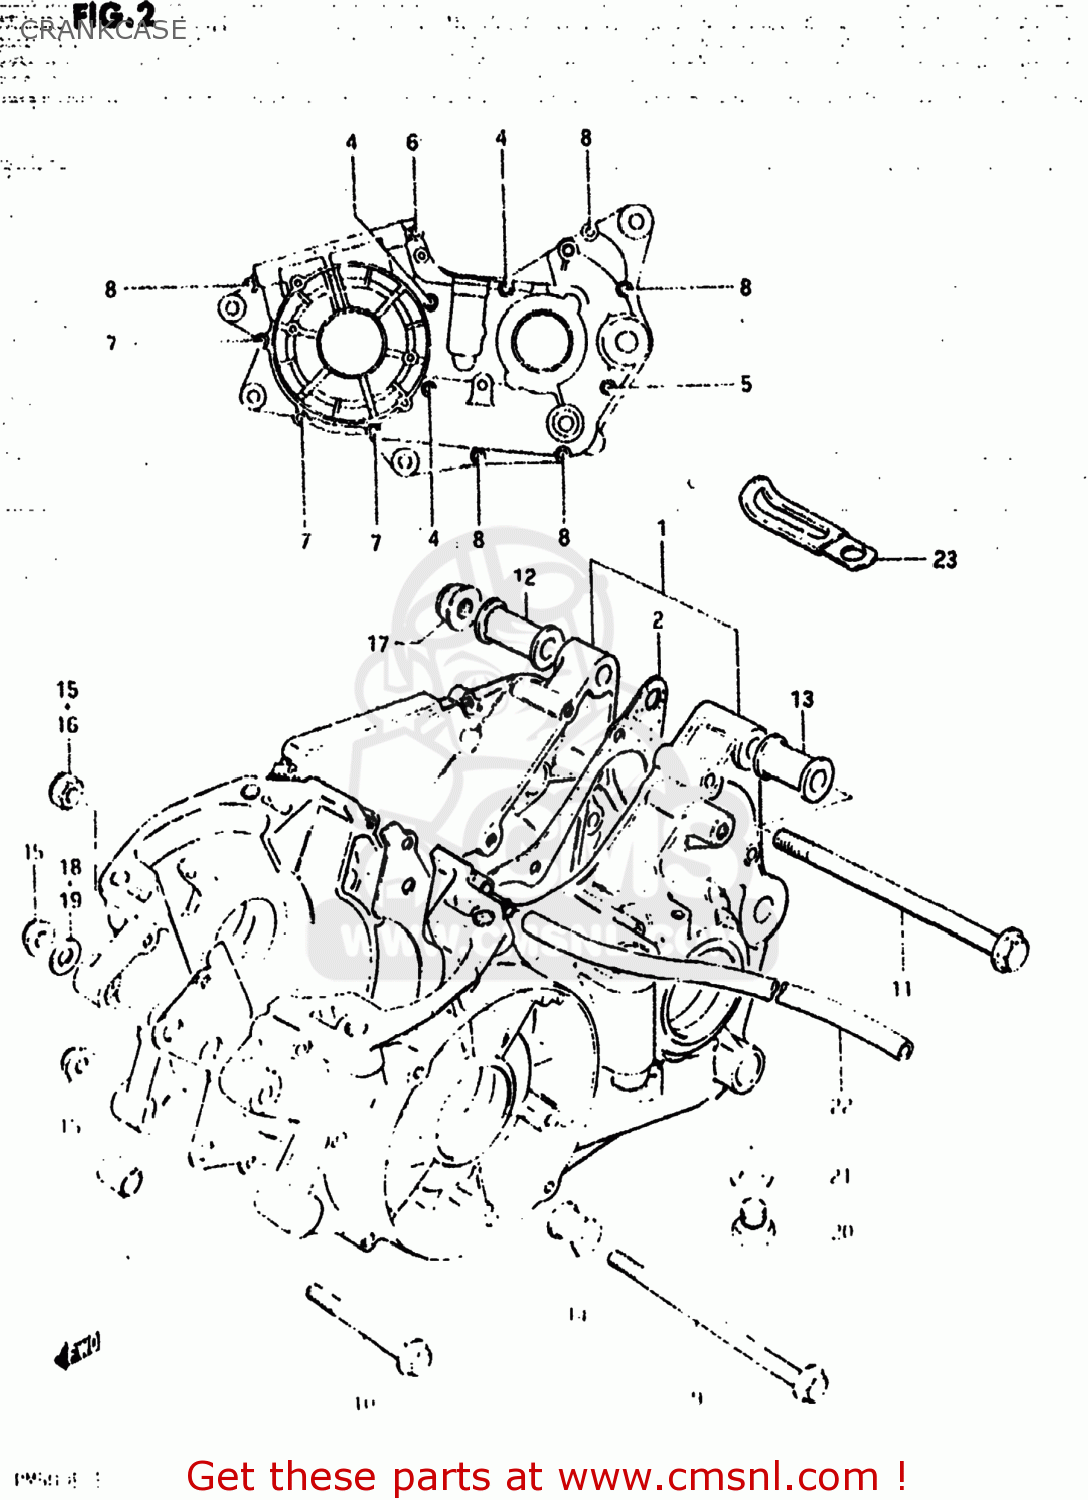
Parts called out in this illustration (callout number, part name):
1	CRANKCASE SET
2	GASKET,CRANKCASE
3	PIN
4	SCREW 6X65
5	SCREW
6	SCREW (6X45)
7	SCREW
8	SCREW (6X35)
9	BOLT 8X200
10	BOLT(8X75)
11	BOLT 10X215
12	SPACER,ENGINE MOUNT
13	SPACER,ENGINE MOUNT
14	SPACER,ENGINE MOUNT
15	NUT
16	NUT
17	NUT
18	WASHER
19	WASHER
20	PLUG
21	GASKET(14X19.2X2) (NAS)
22	HOSE
23	CLAMP
